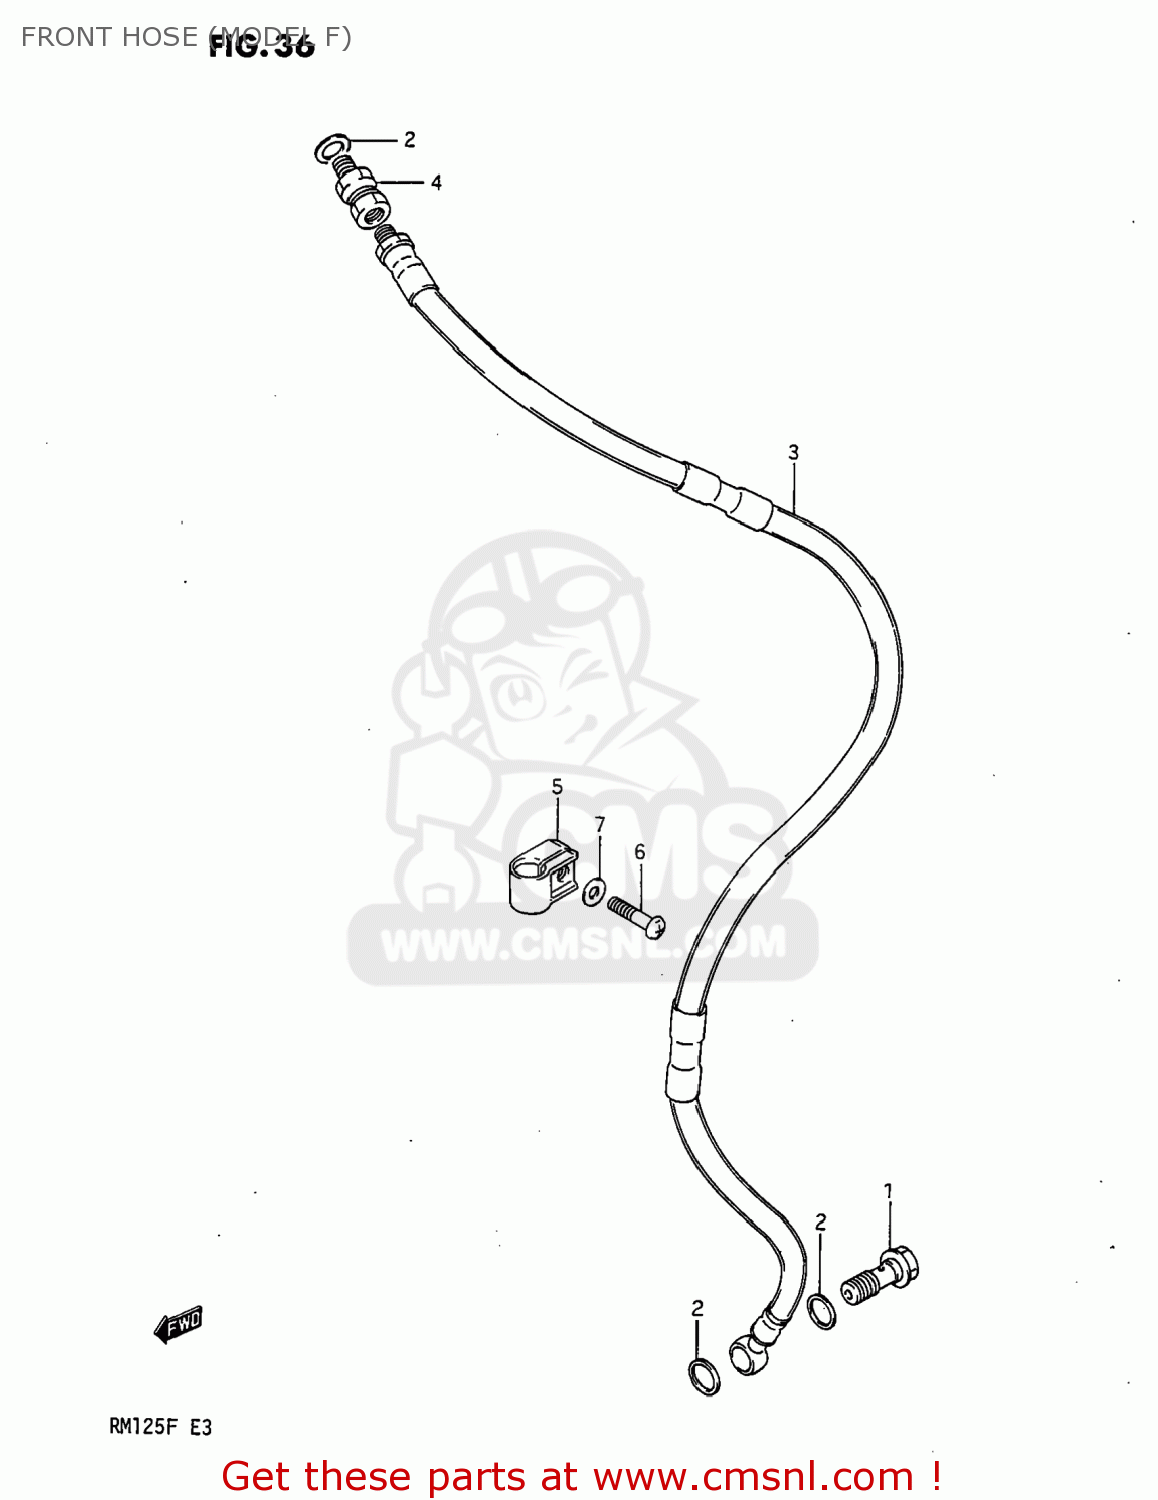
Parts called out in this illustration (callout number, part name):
1	BOLT UNION
2	WASHER(10X15X1.5)
3	HOSE,FRONT BRAKE
4	ADAPTER,BRAKE HOSE
5	CLAMP,FRONT BRAKE HOSE
6	SCREW
7	WASHER
